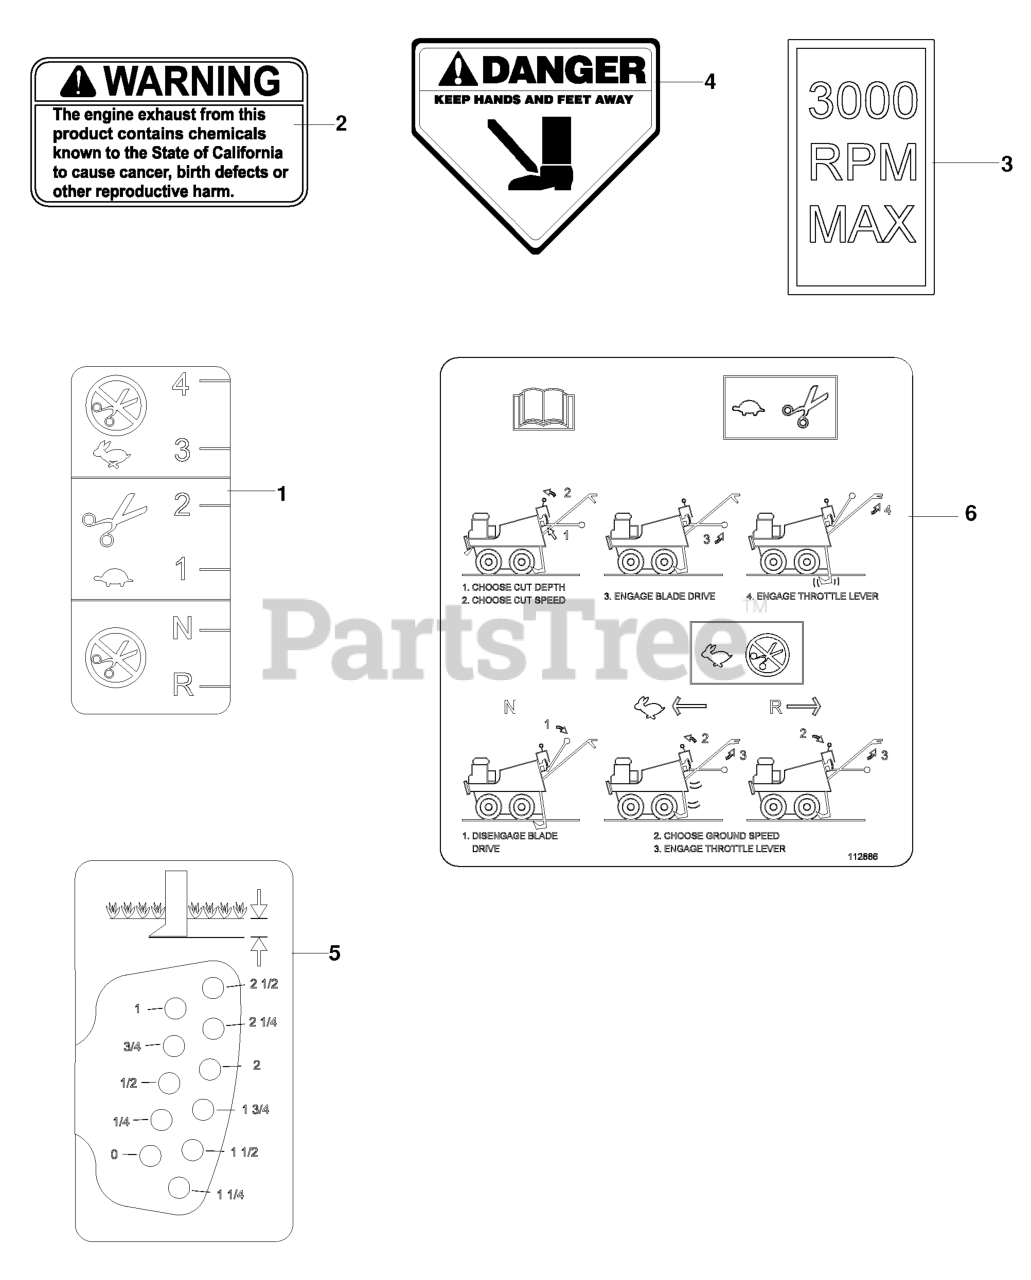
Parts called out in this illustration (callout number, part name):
1	DECAL, SHIFT
2	DECAL, PROP. 65
3	DECAL, 3000 MAX RPM, HUSQ
4	DECAL, FOOT DANGER
5	DECAL, DEPTH OF CUT
6	DECAL, OPERATION
